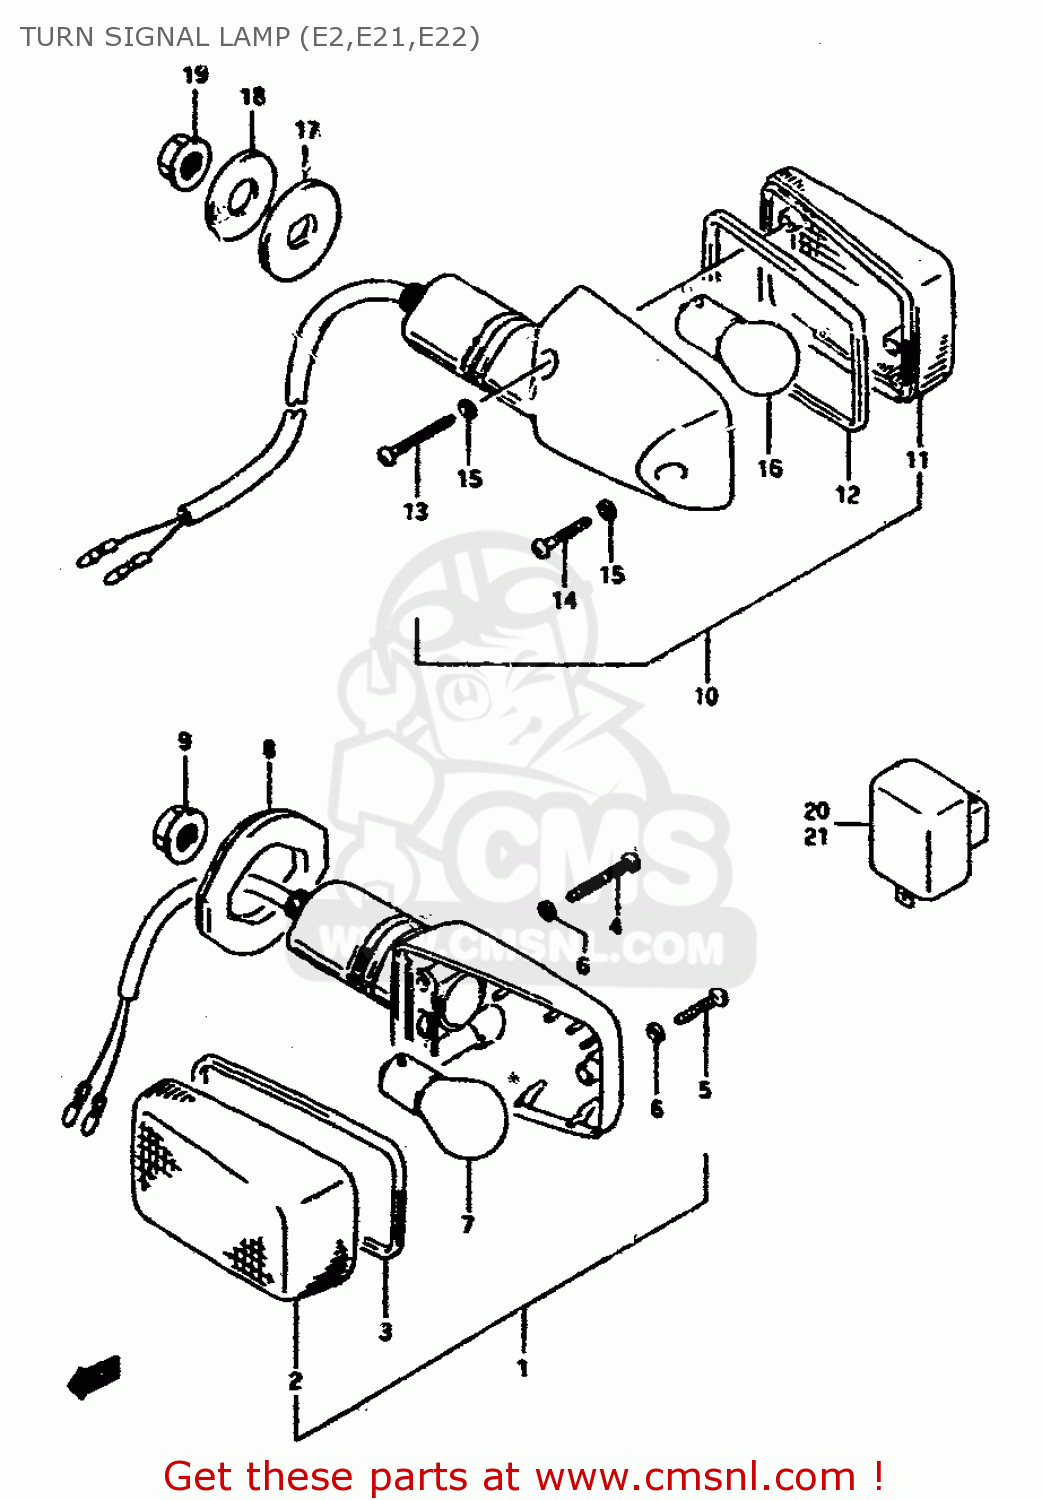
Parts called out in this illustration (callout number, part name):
1	LAMP ASSY,FR TURN SIGNAL
2	LENS
3	GASKET (NAS)
4	SCREW(3X30)
5	SCREW
6	GASKET (NAS)
7	BULB(12V21W)
8	GROMMET
9	NUT
10	LAMP ASSY,RR TURNSIGNAL
11	LENS
12	GASKET (NAS)
13	SCREW(3X30)
14	SCREW
15	GASKET (NAS)
16	BULB(12V21W)
17	SPACER,RR TURNSIGNAL
18	WASHER(10.5X30X3.2)
19	NUT
20	RELAY ASSEMBLY,TURN SIGNAL
21	RELAY ASSY,TUR
